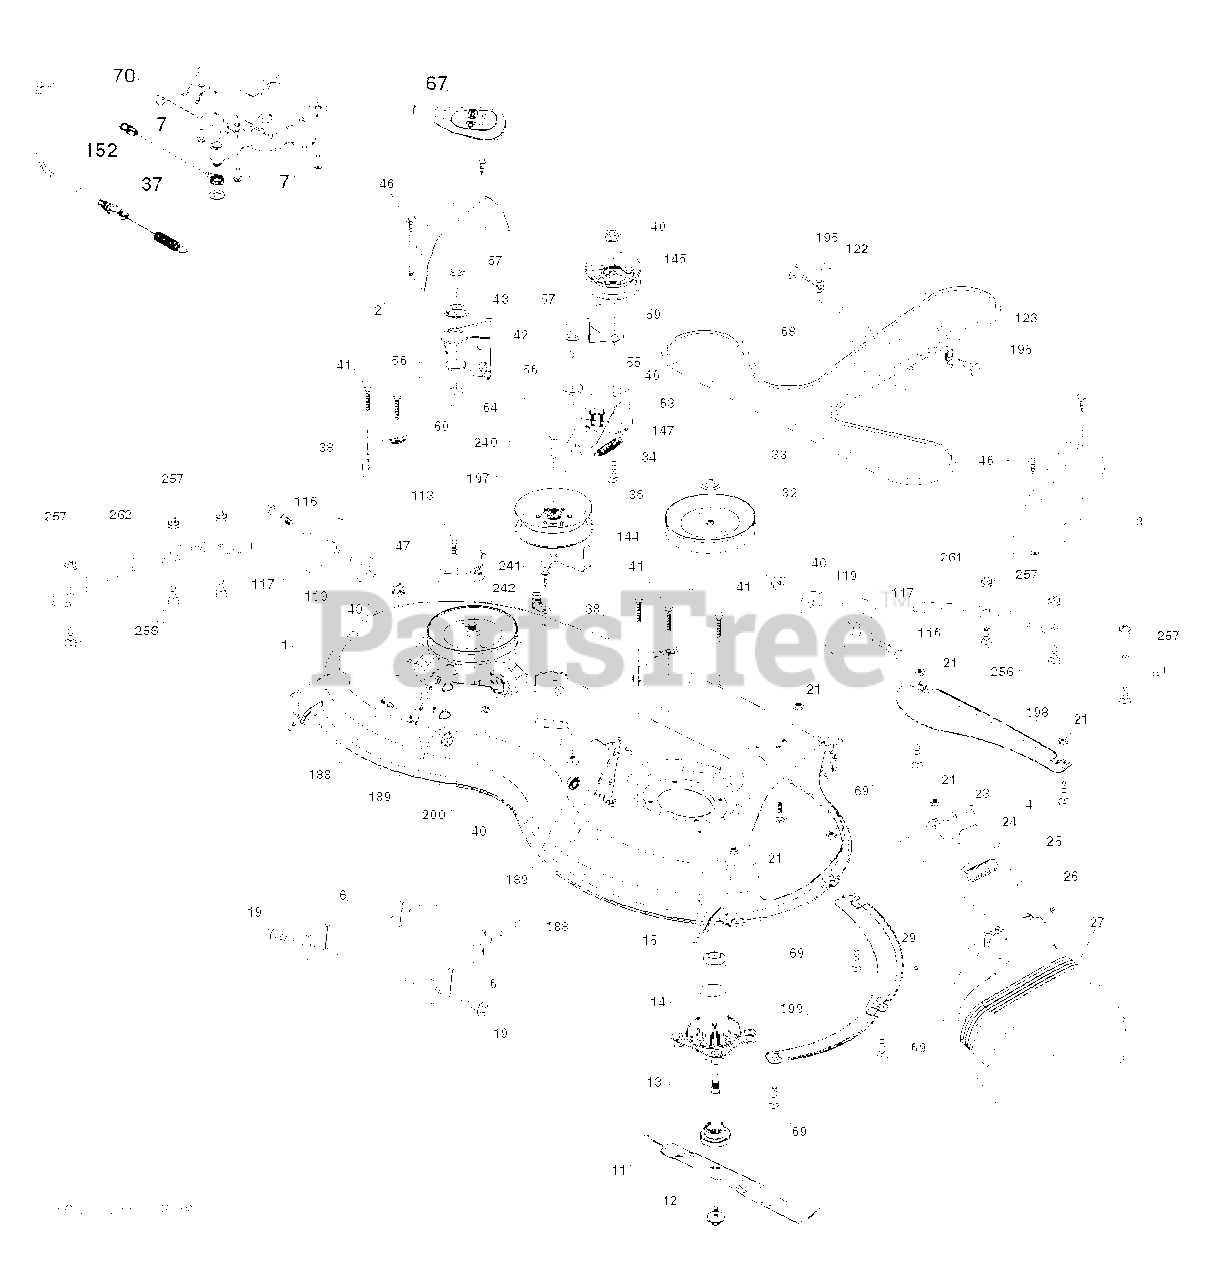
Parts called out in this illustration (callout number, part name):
1	KIT.SVC.WELDMNT.46"405050X498
2	COVER.MANDREL.RH.46"
3	COVER.MANDREL.LH.46"
4	BOLT
6	ARM.SUSPENSION.MOWER.R
7	SCREW.#10 X 0.750.BOS
11	BLADE.MOWER.46".HI.LIFT
12	SCREW.SEMS.7/16-20X1.HEX.HEAD
13	SHAFT ASM.MNDRL.N/GREASEABLE
14	HOUSING.MANDREL.4PT.
15	BEARING.MANDREL.TOP.EXTENDED
19	BOLT.SHOULDER
21	LOCKNUT
23	BRKT.DEFLECTOR.38"2005+
24	CAP-SLEEVE LT
25	SPRING.TORSION.DEFLECT
26	NUT PUSH M
27	SHIELD.DEFLECTOR.MOWER.46"BLAC
29	ROD.HINGE
32	PULLEY.MANDREL.5.438.PD
33	NUT.FLANGE.LOCK.TOP
34	BOLT.3/8-16X1.50
36	PULLEY.IDLER.2006
37	WASHER
38	KEEPER.BELT.MANDREL.PULLEY
40	NUT LOCK FLG 3/8-16 UNC
41	BOLT.HEX.WASHR.HED.313-18X1.19
42	SPRING.TORSION.BRAKE
43	SRPING.TORSION.RETAINE
46	SCREW.1/4-20X5/8
47	BRKT.CLUTCH.CABLE
56	SPACER.RETAINER
57	SCREW 3/8-16X1
59	GUARD, BELT
60	ARM BRAKE MOWER RH 38"
63	ARM BRAKE MOWER
64	LINKAGE BRAKE
67	HANDLE.CLUTCH.CABLE.LT
68	V-BELT
69	BOLT
70	CLUTCH.ASM.MANUAL.YT.PREDATORQ
113	BOLT.5/16HEX.WHS.HD
116	BOLT.SHOULDER.3/8-16X3-5/8.
117	Gage Wheel, Rally
119	WASHER
122	KEEPER BELT ENGINE LH
123	KEEPER BELT RH
144	KEEPER.BELT.MOWER
145	PULLEY.IDLER.48"PRIMARY
147	SPRING RETURN
152	CABLE.MECHANICAL.CLUTCH
188	STUD.FASTNER.W/ANTI-ROTATE
189	NUT LOCK HEX FLANGE 5/16-18
195	SCREW, 3/8-16X3/4
197	WASHER
198	BAFFLE CENTER FRONT
199	BAFFLE FRONT RH
200	WASHER.13/32 X 1 X 1/2.11GUARD
240	BOLT-HEX EAK
241	SCREW.TT.#10-32X.5.3/8.FLANGE
242	PORT.WASHOUT
256	RHSNB, 1/4-20 X 1, GR5
257	NUT T
261	Deck Reinforcement Plate, 46 F
262	PLATE.REINF.DECK.46.S
